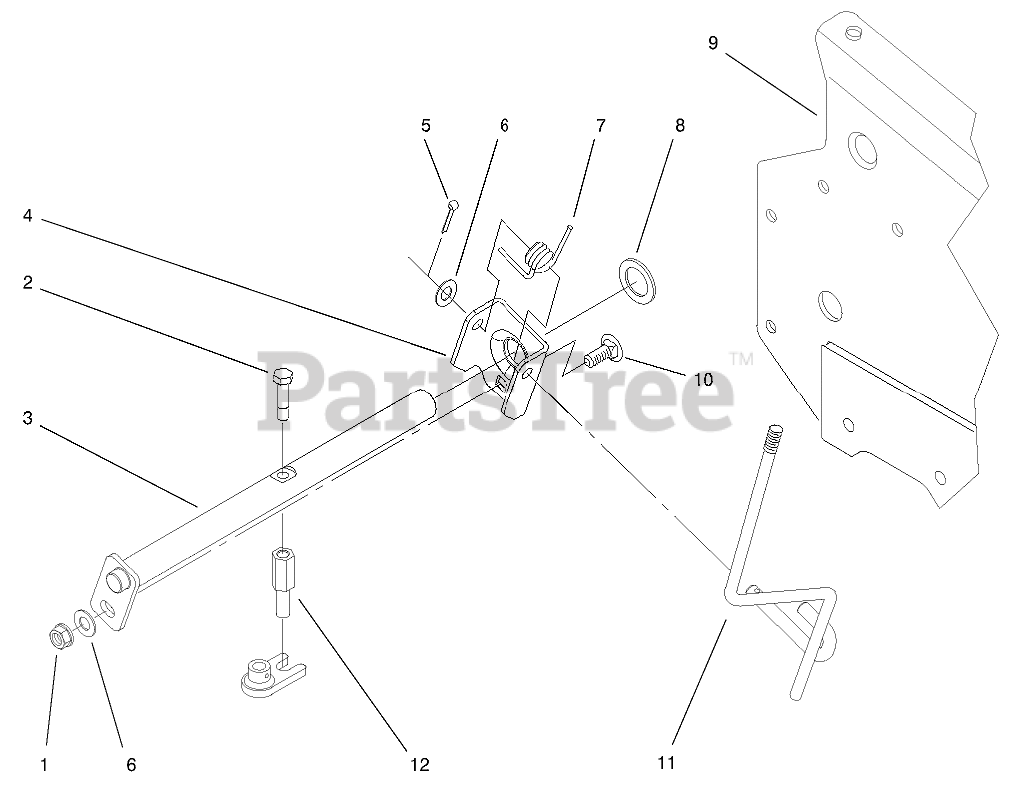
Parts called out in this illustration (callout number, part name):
1	NUT-LOCK, NI
2	SCREW-THREAD LOCKING
3	SHIFT ROD ASM
4	BRACKET-PIVOT
5	PIN-COTTER
6	WASHER-FLAT
7	SPRING-TORSION
8	SPACER
10	SCREW-CARR
11	LEVER-SHIFT
12	ROD-PIVOT, SHIFT
